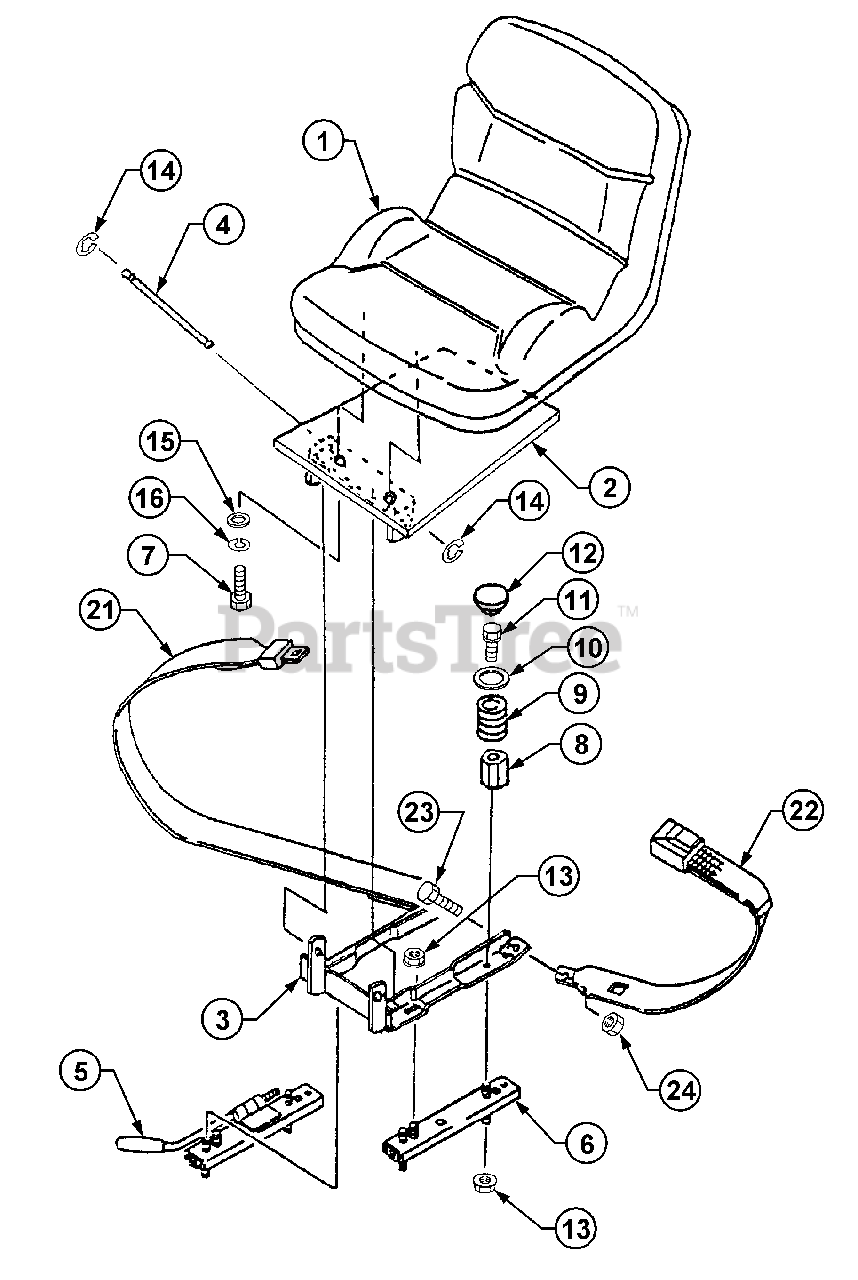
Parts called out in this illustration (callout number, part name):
1	Seat Assy
3	Bracket, Seat
5	Seat Adjuster
6	Seat Adjuster
9	Spring
15	Flat Washer
16	Lock Washer
21	Belt, Body
22	Belt, Body A
